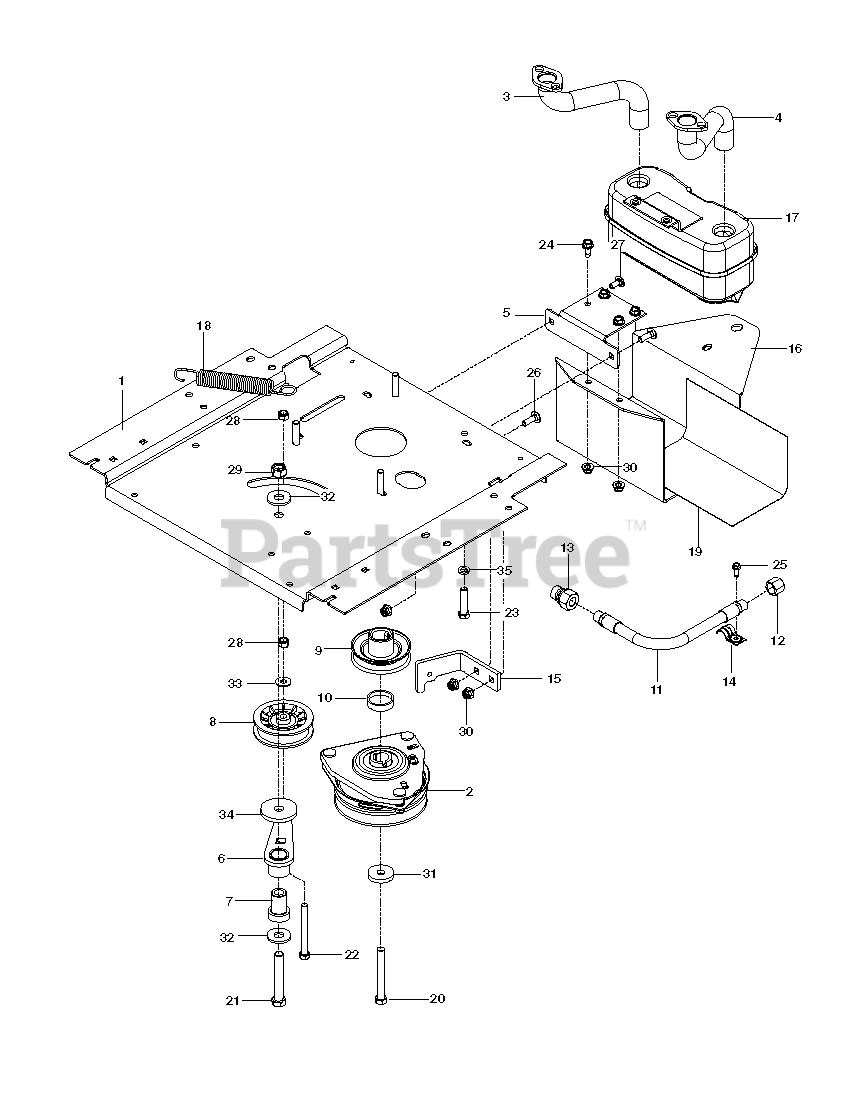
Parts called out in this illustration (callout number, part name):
1	PLATE, ENGINE BLK
3	TUBE.EXHAUST
4	TUBE.EXHAUST
5	BRACKET, MUFFLER, BLACK
6	IDLER ARM
7	IDLER SPINDLE
8	PULLEY, IDLER
9	PULLEY, ENGINE
10	SPACER, HUB PULLEY
11	OIL DRAIN HOSE
12	DRAIN CAP
13	ADAPTER, OIL DRAIN
15	CLUTCH STOP OGR BLK
16	GUARD, MUFFLER, BLACK
17	MUFFLER ASM TWIN
18	SPRING, DECK DRIVE
19	HEAT SHIELD
20	HCS 7/16-20 X 2.5 GR8
21	HCS 1/2C X 3 1/4
22	HCS 3/8-16X3 1/2 GR5
23	BOLT, HCS 3/8-16X1-3/4
24	BOLT 5/16-18 X 3/4
25	SCREW 1/4 X 5/8
26	RHSNB 5/16C X 1
27	BOLT 5/16C X 3/4" CARRIAGE
28	NUT 3/8-16 NYLOC
29	NUT 1/2-13 HEX NYLOC ZD
30	5/16-18 NYLOC FLANGE NUT
32	WASH USS FLAT 1/2
33	WASHER 5/16 FLAT
34	HEAVY WASHER
35	SLW 3/8 STD
